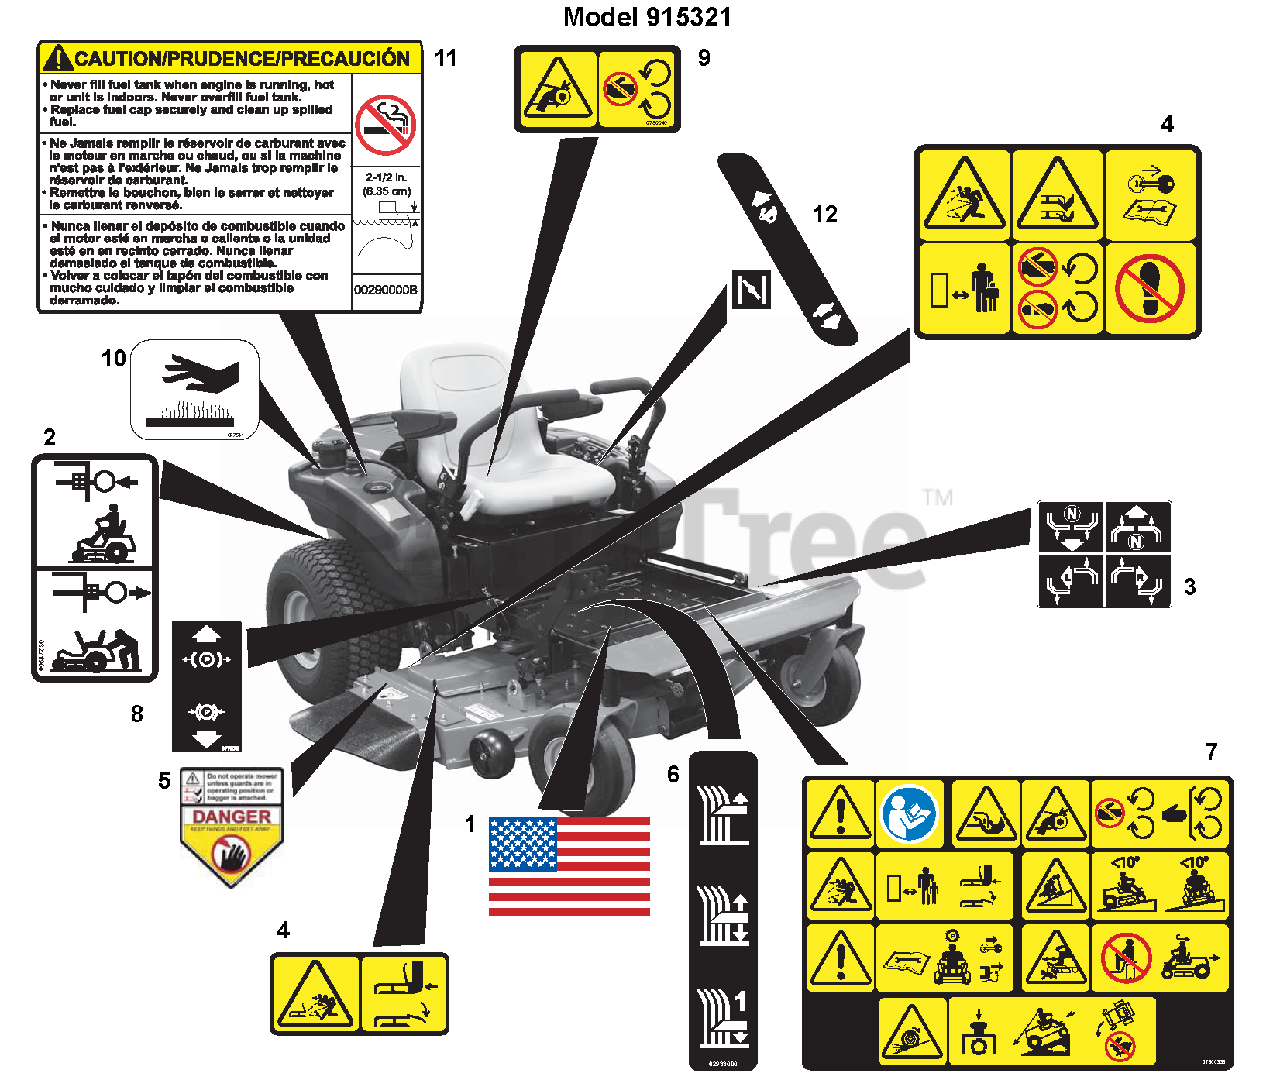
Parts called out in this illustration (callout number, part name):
1	DECAL, AMERICAN FLAG
2	DECAL, TRANSMISSION DISCONNECT
3	DECAL, INSTRUCTIONAL-STEERING
4	DECAL, SAFETY - DECK GUARDING
5	DECAL, DANGER
6	DECAL, CUT HEIGHT
7	DECAL, SAFETY - MAIN
8	DECAL, PARKING BRAKE LEVER
9	DECAL, SAFETY - GUARDING
10	DECAL, HOT SURFACE
11	DECAL,FUEL WARNING
12	DECAL, SPEED CONTROL
